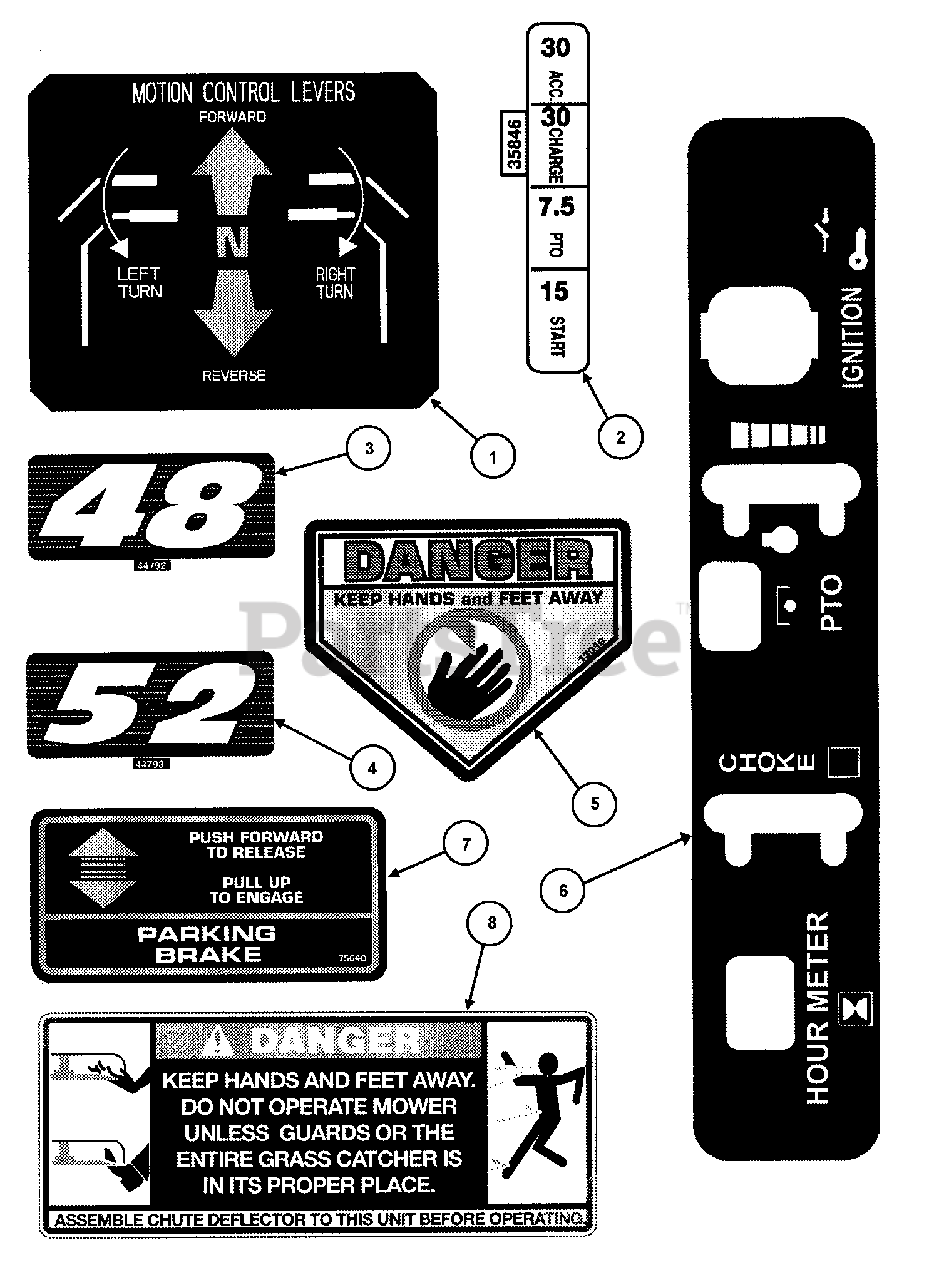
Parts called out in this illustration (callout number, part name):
1	DECAL,Motion Control Lever
2	DECAL, Fuse
3	DECAL, 48" Deck (Series 0)
4	DECAL, 52" Deck (Series 0)
5	DECAL, Warning (CPSC Cut-Finger)
6	DECAL, Control Panel
7	DECAL, Park Brake
8	DECAL, Danger, Guard/Catcher
